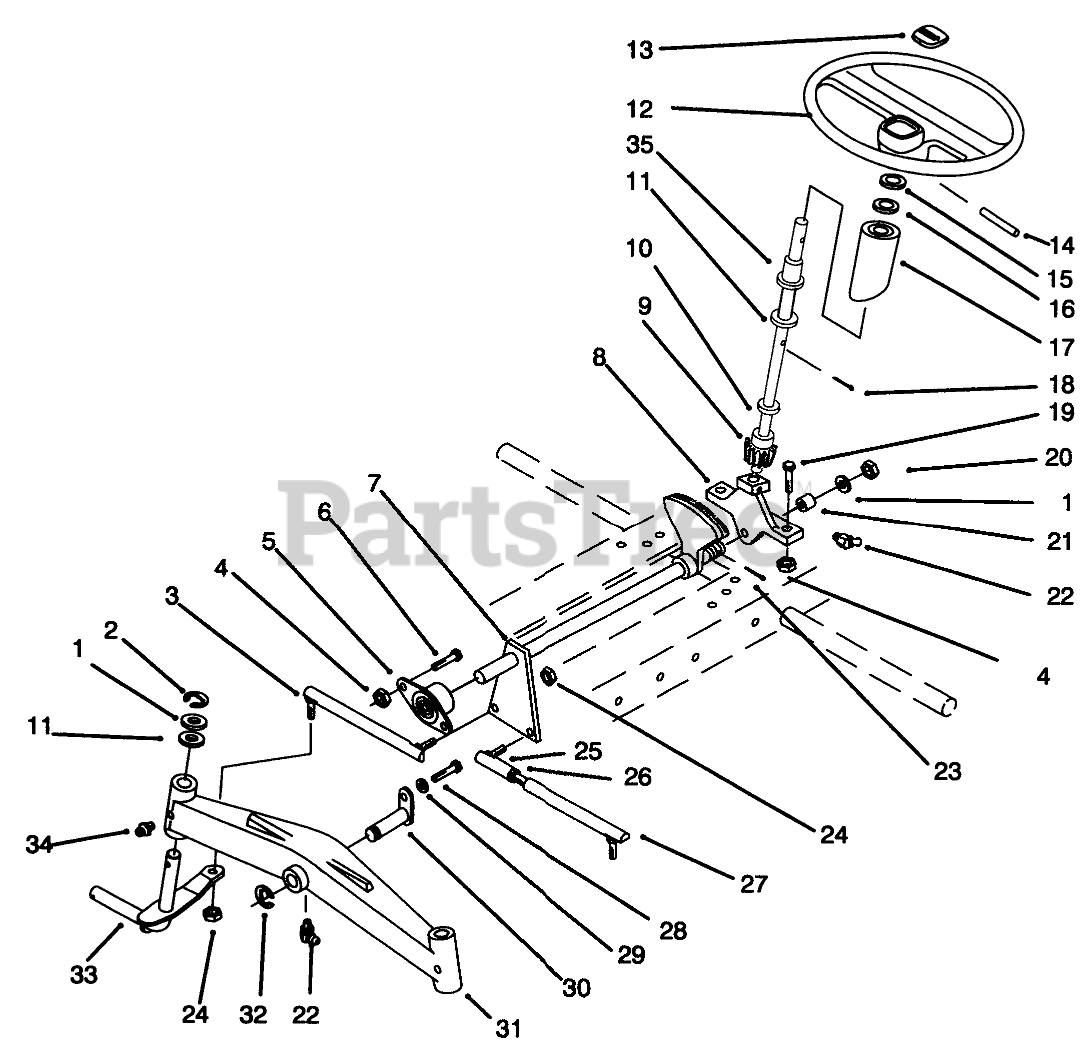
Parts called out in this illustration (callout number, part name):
1	WASHER
2	RING-RETAINING
3	Tie Rod RH
4	NUT-LOCK, NI
5	BEARING-FLANGED
6	SCREW-HH
7	Shaft
8	Support-Steering Shaft
9	STEERING SHAFT ASM
10	O-RING
11	WASHER-SHIM
12	Steering Wheel (Incl. Ref. #13)
13	STRG-WHL INSERT TORO
14	PIN-ROLL
15	WASHER-BOWED
16	WASHER-FLAT
17	TUBE-STEERING
18	PIN-COTTER
19	SCREW-HH
20	NUT-HEX, SLOTTED
21	BEARING-BRONZE
22	FITTING-GREASE
23	PIN-COTTER
24	NUT-LOCK
25	BALL-JOINT
26	NUT-HEX
27	Tie Rod Assembly, LH (Incl. Ref. #25 & 26)
28	SCREW-HH
29	WASHER-LOCK
30	PIN AND PLATE ASM
31	AXLE-FRONT
32	E-RING
33	LH SPINDLE ASM
34	FITTING-GREASE
35	BEARING-FLANGED
